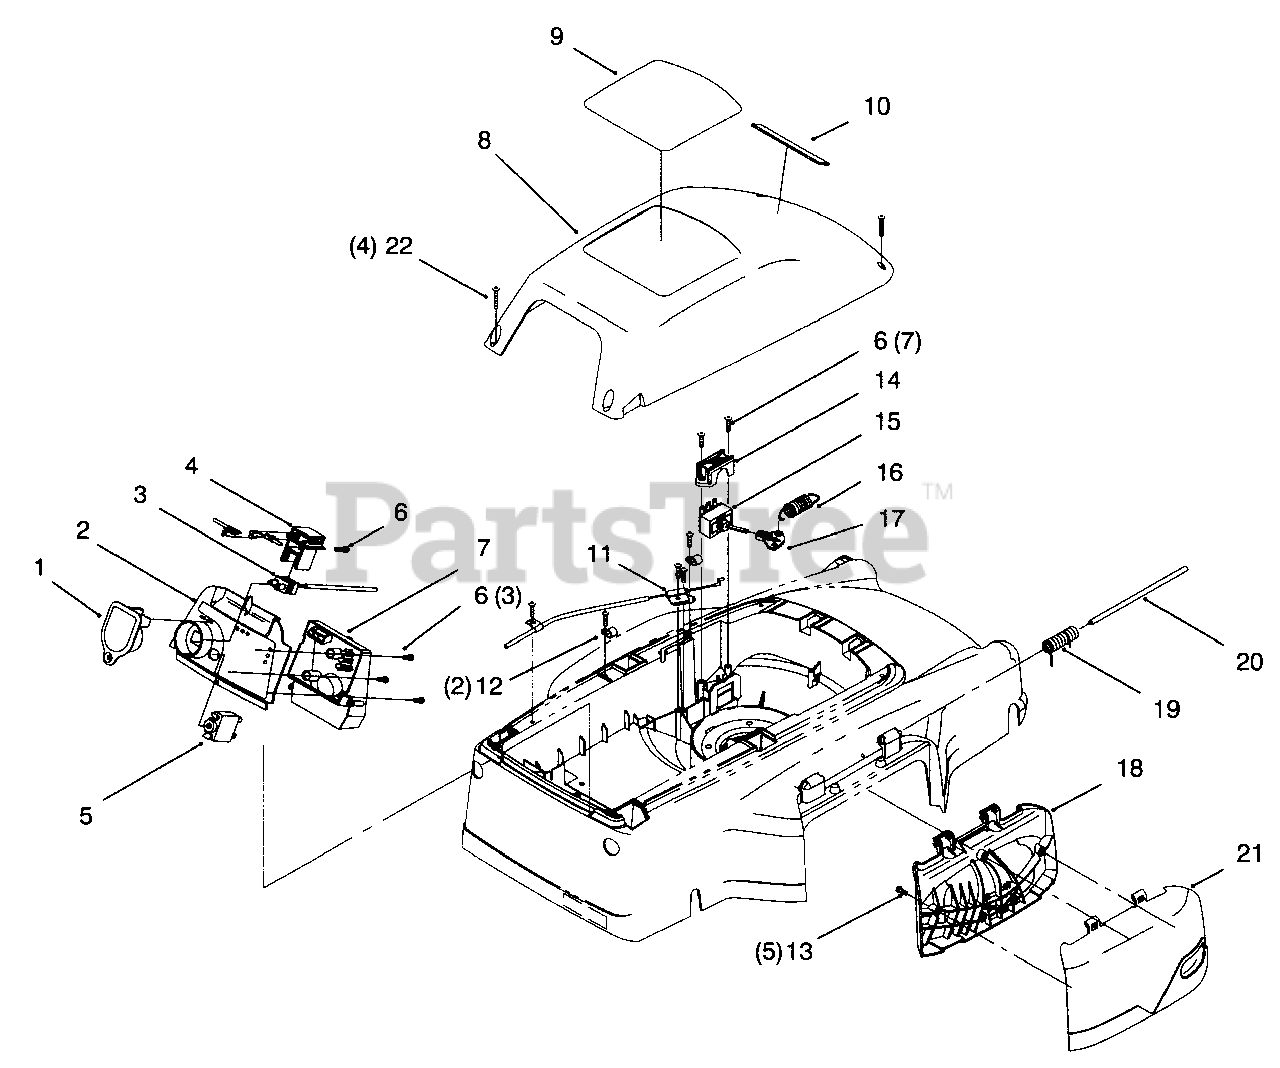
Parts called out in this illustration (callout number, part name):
2	ASM-Panel
3	ASM-Plug
4	Housing-Plug
5	Circuit Breaker
6	Screw-PH
7	ASM-Charger
8	ASM-Cover
9	Decal-Cover
10	Applique-Shroud
11	Bracket-Cable
12	Clamp-Cable
13	Screw-PH
14	Clamp-Switch
15	Switch-Toggle
16	Spring-Switch
17	Cover-Lever
18	Mulch Plug-Inside
19	Spring-Torsion
20	Pin-Hinge
21	Mulch Plug Outside
22	Screw-PPH
